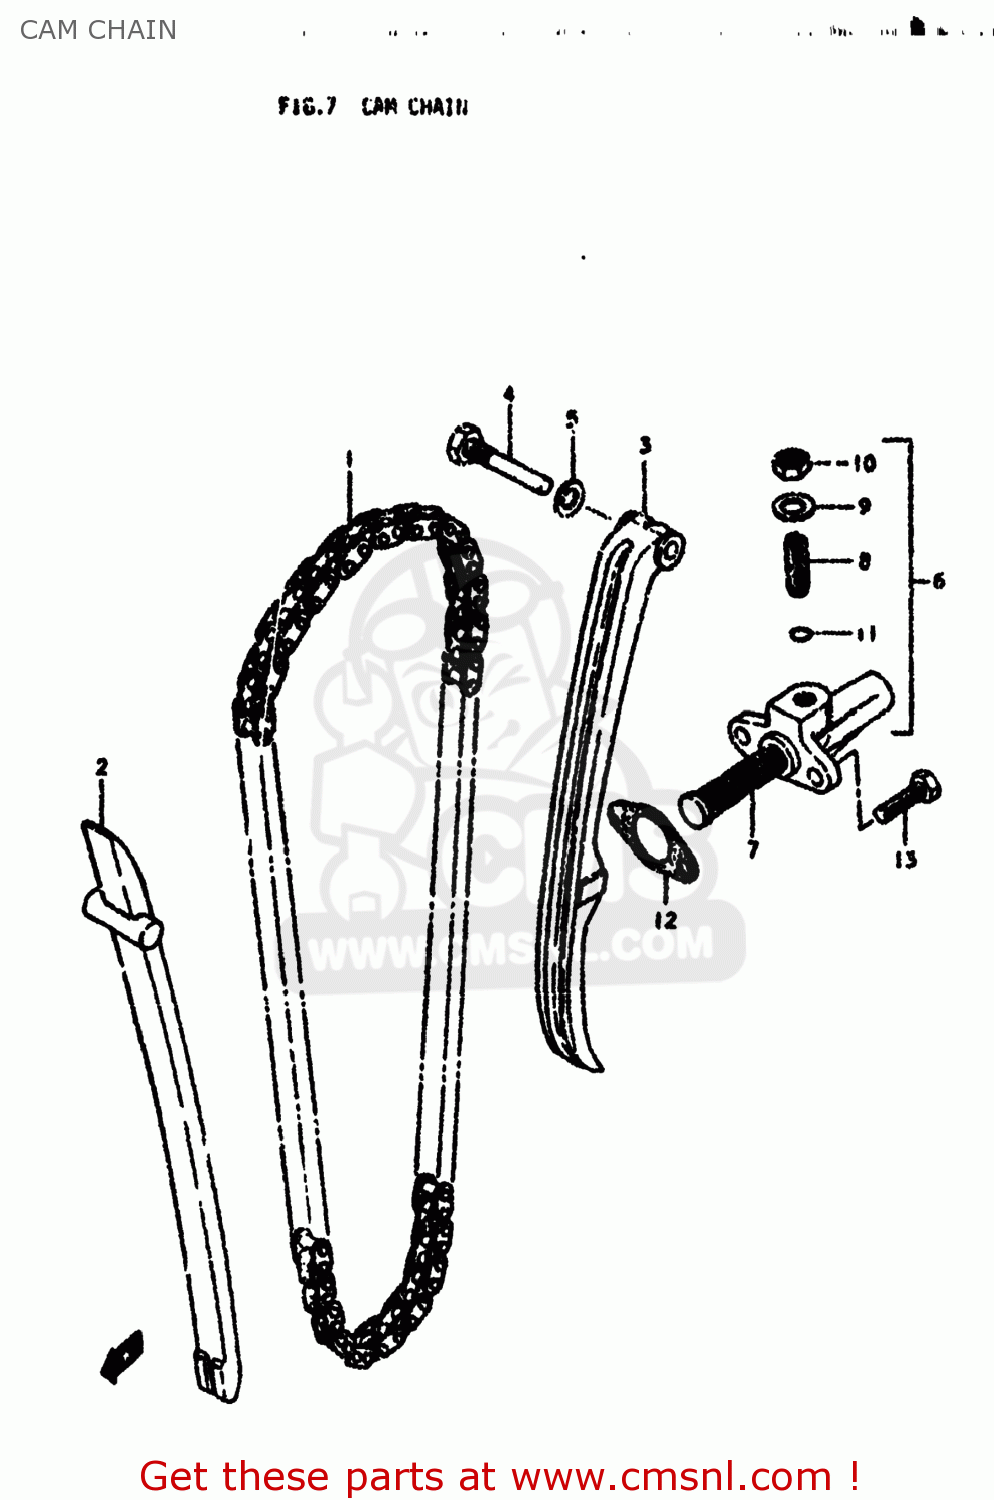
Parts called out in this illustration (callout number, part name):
1	CHAIN,CAMSHAFT DRIVE
2	GUIDE,CAM CHAIN
3	TENSIONER,CAM CHAIN
4	BOLT
5	GASKET 8.2X14X1 (NAS)
6	ADJUSTER ASSEMBLY,TENSIONER
7	SPRING
8	SCREW
9	WASHER
10	NUT
11	O-RING
12	GASKET,TENSIONER ADJUSTER (NAS)
13	BOLT
